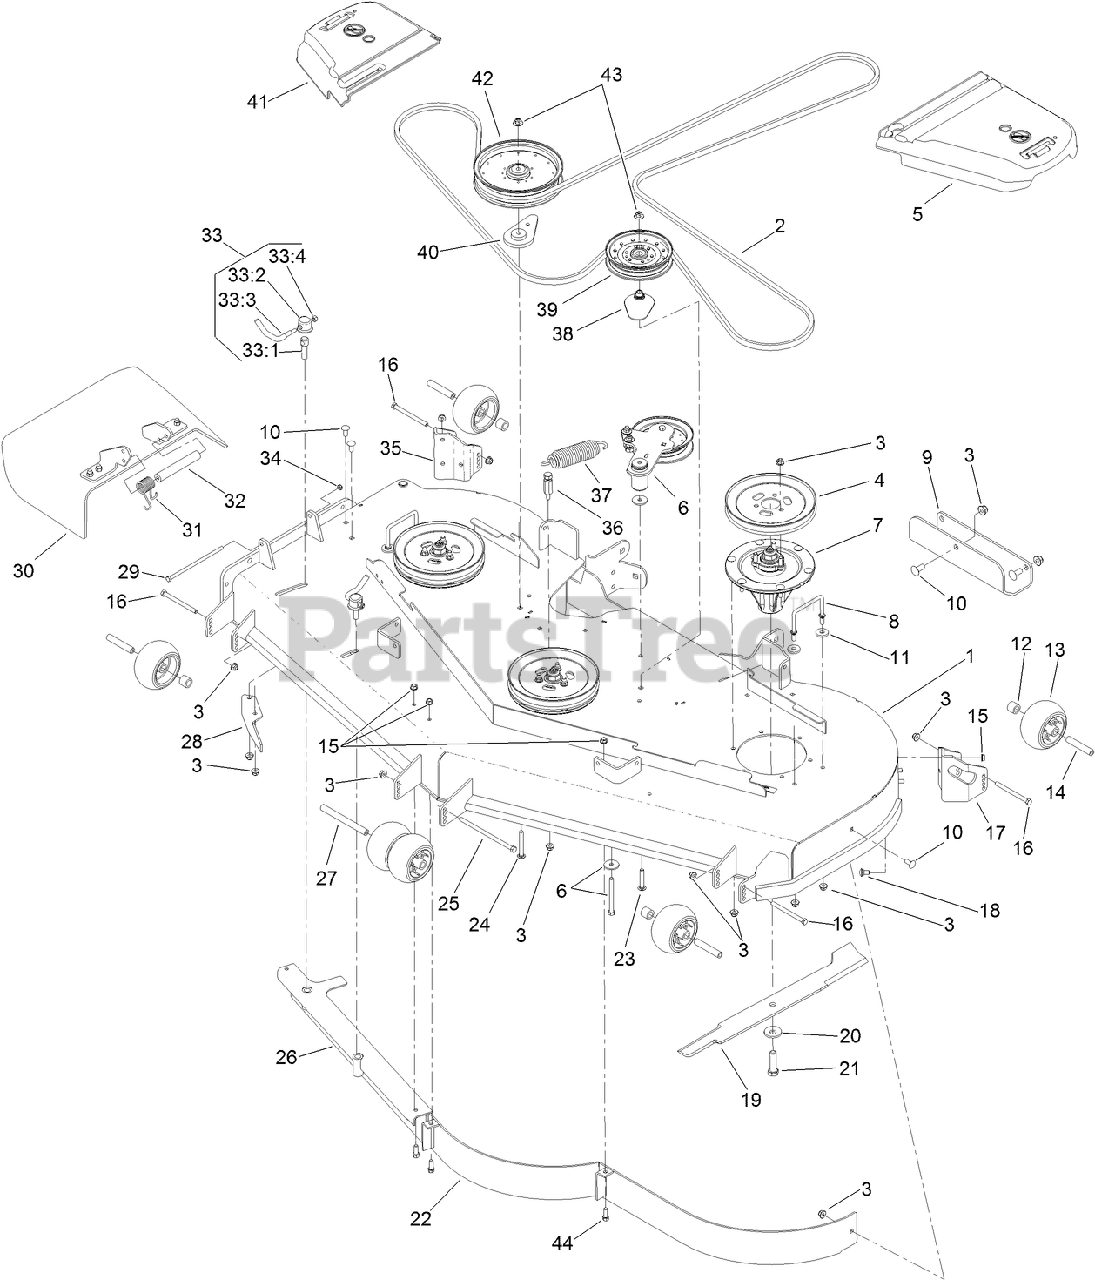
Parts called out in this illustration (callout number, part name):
1	DECK DECAL ASM
2	BELT-V
3	NUT-HF, NI
4	Pulley
5	COVER-BELT, LH
6	IDLER ARM ASM
7	SPINDLE ASM
8	WIREFORM-COVER
9	PLATE-SKID
10	SCREW-CARR
11	WASHER
12	TUBE-SPACER
13	ROLLER-SCALP, ANTI
14	TUBE-SPANNER
15	NUT-HHF, WHIZ
16	SCREW-HH
17	MOUNT-WHEEL, LH
18	SCREW-CARR
19	BLADE-HI FLOW, 24.5 INCH
20	Washer-Blade Bolt, Heavy
21	SCREW-BLADE
23	BOLT-CARR, SHORT NECK
24	SCREW-CARR
25	SCREW-HH
26	BAFFLE ASM
27	SPACER-WHEEL
28	BAFFLE-DISCHARGE
29	SCREW-HH
30	RUBBER DEFLECTOR ASM
31	SPRING-TORSION
32	SPACER
33	LEVER ASM
33:1	Screw-Lock
33:2	CAP-LOCK
33:3	Lever-Lock
33:4	NUT-LOCK, NI
34	NUT-LOCK, NI
35	MOUNT-WHEEL, RH
36	ANCHOR-SPRING, TALL
37	SPRING-EXTENSION
38	SPACER-PULLEY
39	PULLEY-IDLER, FLAT
40	SPACER-IDLER
41	COVER-BELT, RH
42	PULLEY-IDLER
43	NUT-FLANGE, NI
44	SCREW-HWH
